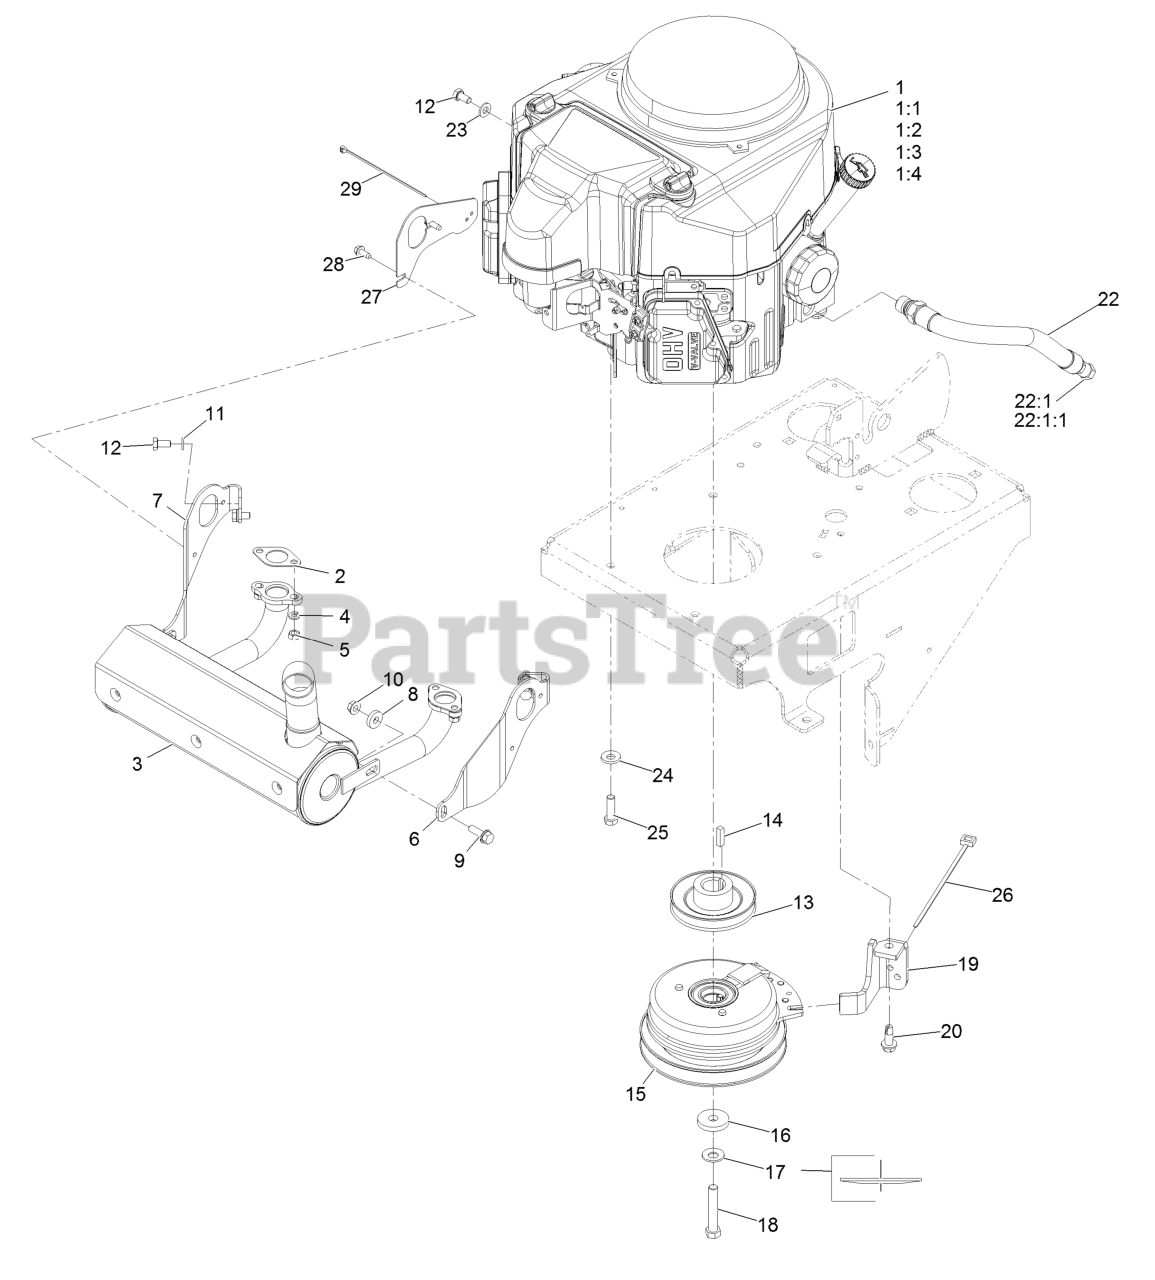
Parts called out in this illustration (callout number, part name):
1:1	Spark Plug
1:2	Filter-Oil
1:3	Filter-Fuel
1:4	Element-Filter, Air
2	Gasket-Exhaust
3	Muffler
4	Washer-Spring Lock M8
6	Bracket-Muffler Mount, LH
7	Bracket-Muffler Mount, RH
9	Screw-HH Flg 5/16-18 X 1
10	Nut-Hex 5/16-18 Side Lock
11	Washer-Lock 5/16
12	Screw-HH M8-1.25 X 16Mm
14	Key-Machine 1/4 X 1/4 X 1
15	Clutch-175 Ft-Lb
16	Washer
17	Washer-Spring Disc 7/16
18	Screw-HH 7/16-20 X 2 1/2
19	Anchor-Clutch
20	Screw-Tapping
22	Asm-Hose Oil Drain W/Plug
22:1	Plug-W/O-Ring
22:1:1	O-Ring
24	Washer-Spring Disc 3/8
25	Screw-HH 3/8-16 X 1 1/4
26	Tie-Cable
27	Guard-Cable, Spark Plug
28	Screw-HWH 1/4-20 X .62
29	Tie-Cable 5 1/2 (Small)
